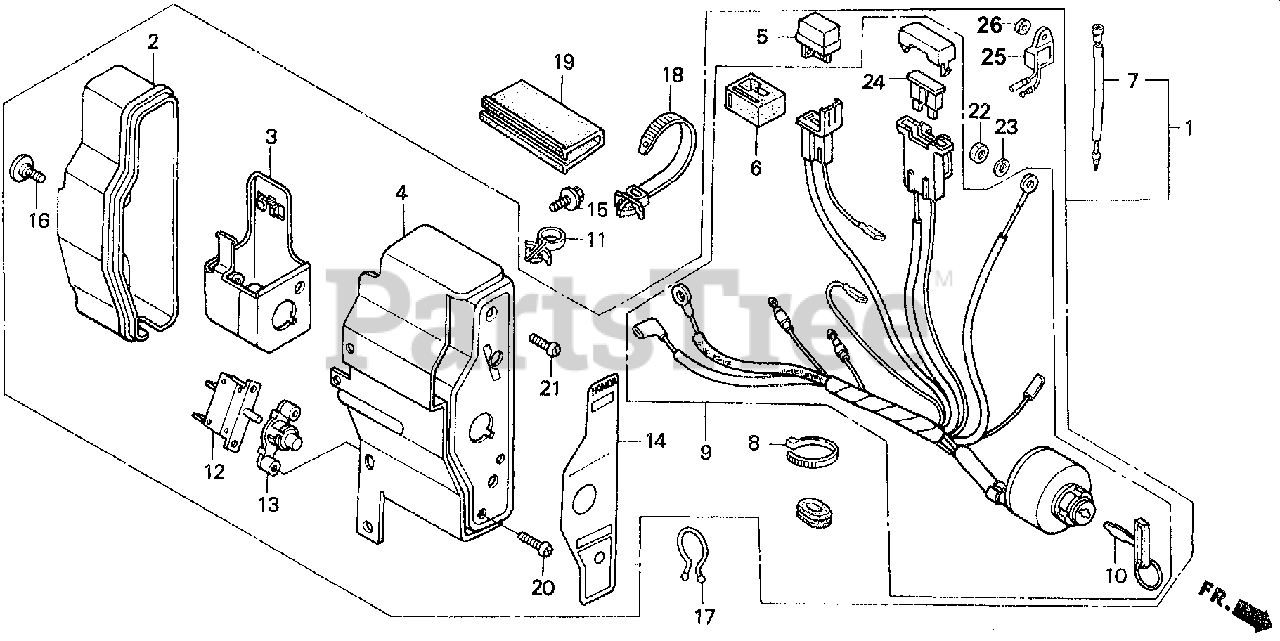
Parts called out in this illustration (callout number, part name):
1	BOX ASSY., CONTROL (EXTERNAL-ALERT/3A) *R8* (BRIGHT RED)
2	CASE, CONTROL
3	BRACKET, CASE MOUNTING
4	PANEL, CONTROL *R8* (BRIGHT RED)
5	RECTIFIER ASSY., SILICON (STANLEY)
6	SUSPENSION, CONNECTOR
7	SUB-HARNESS
8	BAND
9	SWITCH ASSY., COMBINATION
10	KEY
11	HOLDER, STOP SWITCH WIRE
12	PROTECTOR, CIRCUIT (3.5A)
13	LENS ASSY., PROTECTOR
14	PANEL, CONTROL BOX (EXTERNAL)
15	BOLT, FLANGE (6X12) (CT200)
16	SCREW, SPECIAL (6X12)
17	CLIP, PURSE LOCK
18	STRAP, CABLE (118MM) *NH1L* (BLACK)
19	TUBE, FASTENER (30)
20	SCREW, PAN (3X12)
21	SCREW, PAN (4X12)
22	NUT, HEX. (4MM)
23	WASHER, SPRING (4MM)
24	FUSE, BLADE (15A)
25	ALERT UNIT, OIL
26	WASHER, PLAIN (4MM)
